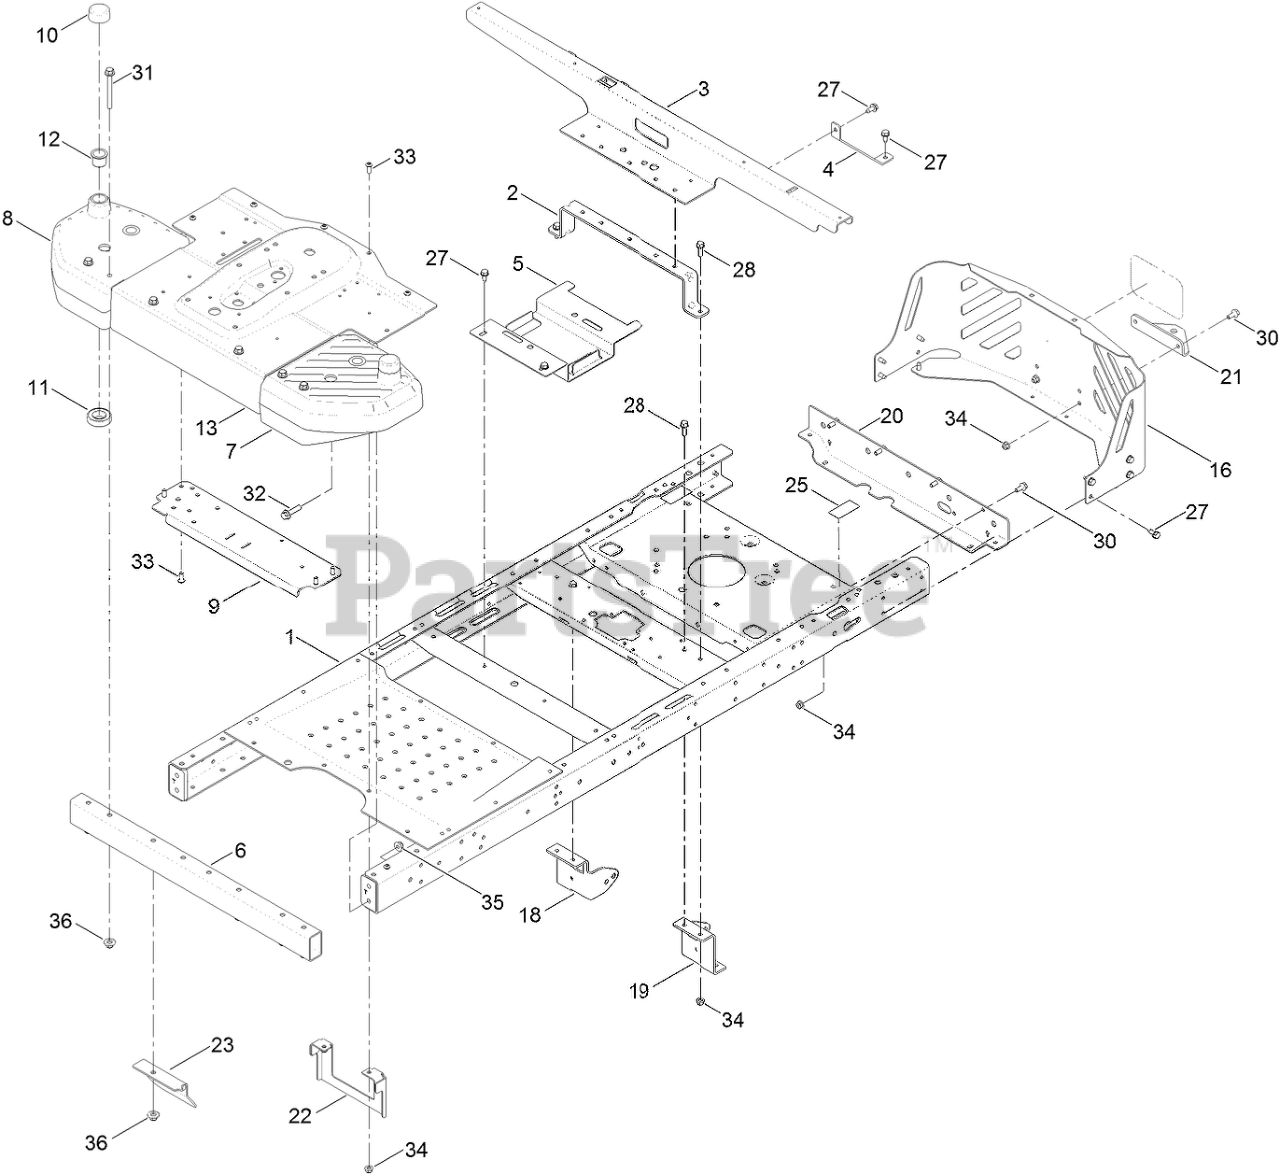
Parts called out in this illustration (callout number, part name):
1	FRAME ASM (WIDE)
2	BRACE-SEAT, REAR
3	SUPPORT-POD, WIDE
4	SUPPORT-TANK, REAR
5	BRACKET-BATTERY
6	TUBE-FRONT, WIDE
7	HOUSING-SPINDLE, LH
8	HOUSING-SPINDLE, RH
9	PLATE-BRIDGE, WIDE
10	CAP-CASTER
11	BEARING-BALL
12	BUSHING-PIVOT
13	PAN-STEER, FRONT
16	GUARD-ENGINE, WIDE
18	MOUNT-HYDRO, FRONT (RH)
19	MOUNT-HYDRO, FRONT (LH)
20	CROSSMEMBER-REAR, WIDE
21	BRACKET-HITCH
22	BRACKET-UPSTOP
23	GUARD-FRONT
25	DECAL-BYPASS
27	SCREW-HWHTF
28	SCREW-HHF
30	SCREW-HHF
31	SCREW-HHF
32	SCREW-HHF
33	SCREW-HSBH
34	NUT-HF, NI
35	NUT-HF, NI
36	NUT-FLANGE, NI
